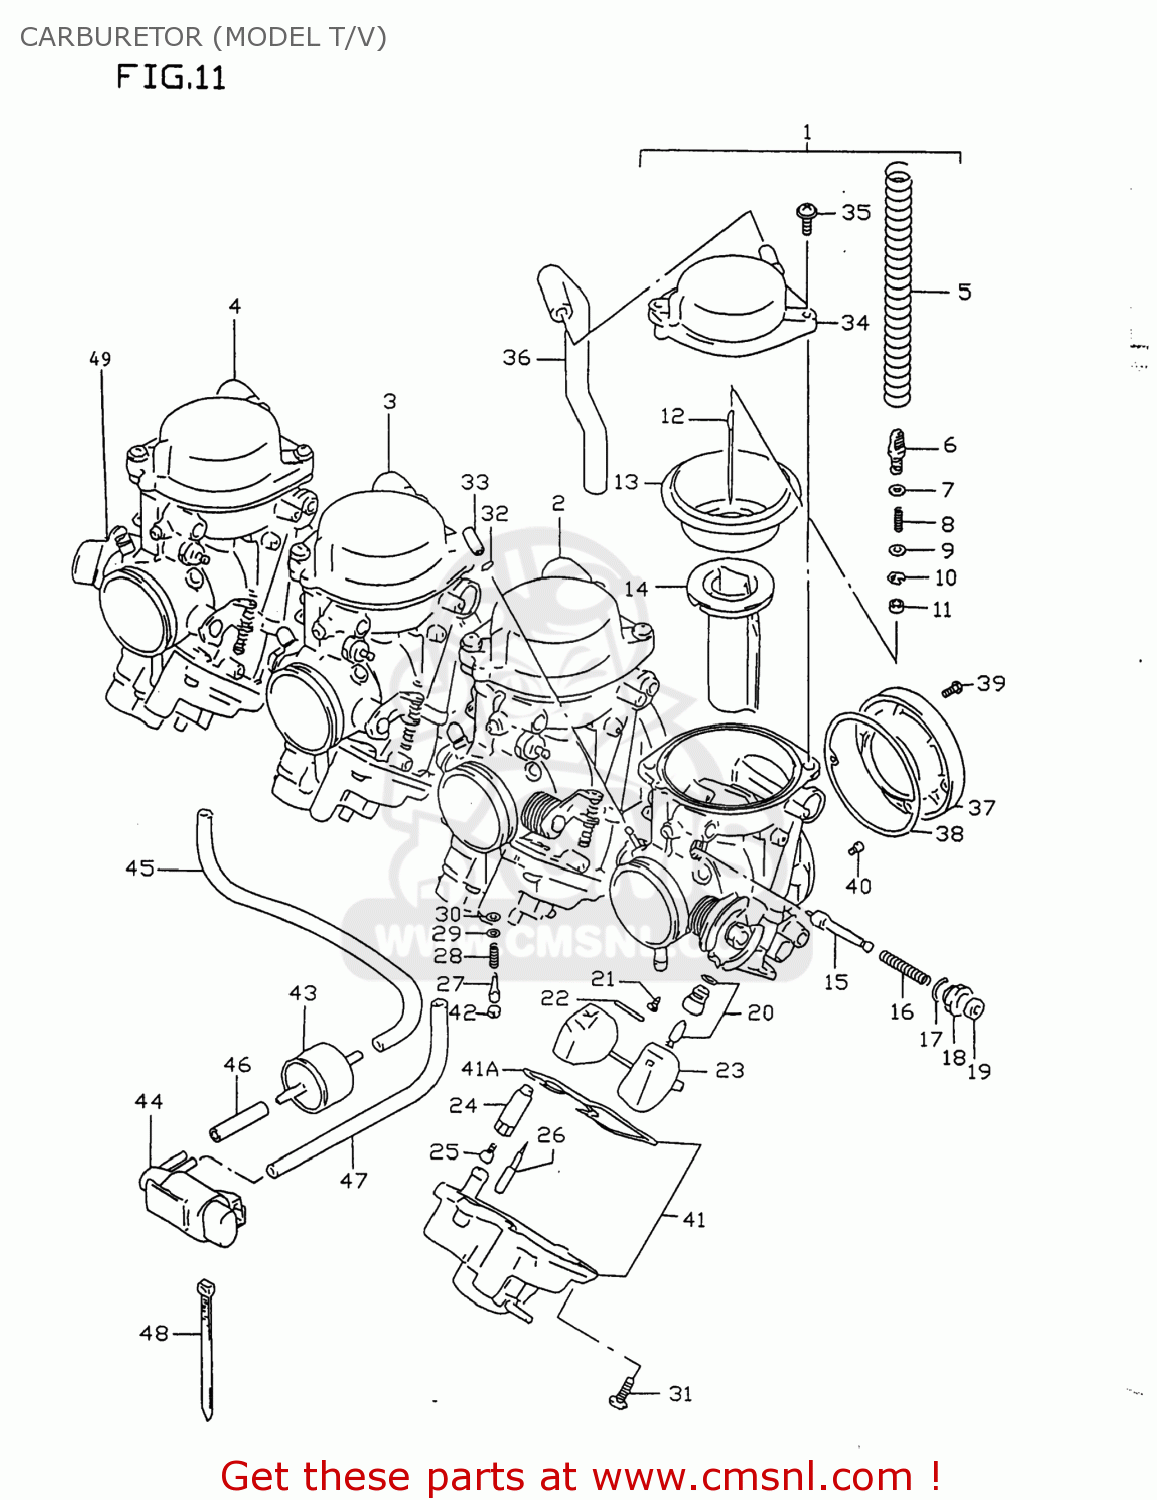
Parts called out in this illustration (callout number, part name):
1	CARBURETOR ASSEMBLY,LEFT
2	CARBURETOR ASSEMBLY,MIDDLE,LEFT
3	CARBURETOR ASSEMBLY,MIDDLE,RIGHT
4	CARBURETOR ASSEMBLY,RIGHT
5	SPRING
6	HOLDER
7	O RING(D:1.9,ID:4.8)
8	SPRING
9	WASHER
10	E RING,MULTIPLE JET NOZZLE
11	RING
12	JET,NEEDLE(6E41-55)
13	DIAPHRAGM
14	VALVE,PISTON
15	PLUNGER
16	SPRING
17	O RING
18	GUIDE SCREW,PLUNGER
19	CAP,STARTER VALVE
20	VALVE ASSEMBLY,NEEDLE
21	SCREW
22	PIN,FLOAT
23	FLOAT ASSY
24	HOLDER,JET
25	JET,MAIN(125)
26	JET,PILOT(12.5)
27	ADJUSTER
28	SPRING,THROTTLE SCREW
29	WASHER
30	O RING,PILOT AIR SCREW
31	SCREW
32	CLIP
33	CAP
34	COVER ASSY
35	SCREW
36	HOSE
37	FUNNEL
38	GASKET
39	SCREW
40	JET,PILOT(127.5)
41	BODY ASSEMBLY,FLOAT,LEFT
41A	O RING
42	PLUG
43	VALVE,VACUUM TRANSMITTING
44	VALVE ASSY,3WAY SOLENOID
45	HOSE(4X8X600)
46	HOSE(4X8X600)
47	HOSE(4X8X600)
48	CLAMP(L:95)
